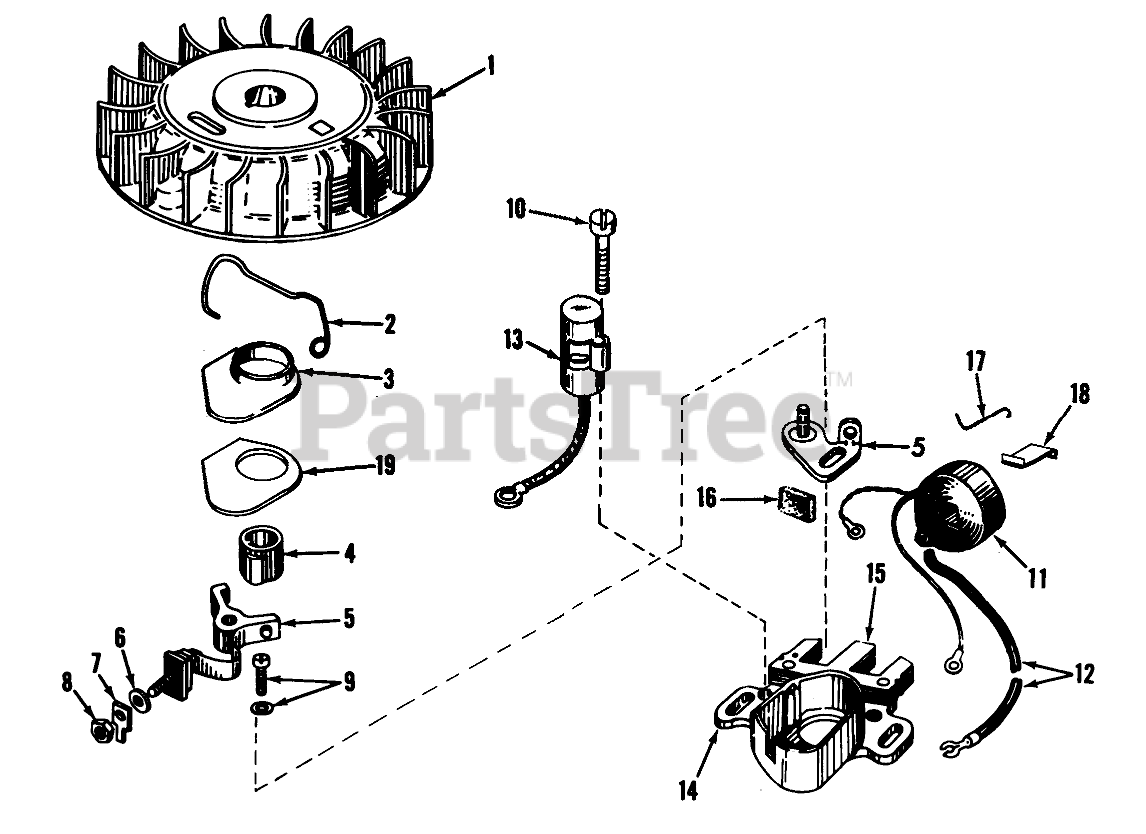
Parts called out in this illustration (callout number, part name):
1	Flywheel
2	Spring Breaker Box
3	Cover, Dust
4	Cam, Breaker
5	Breaker Assy.
7	Terminal
9	Breaker Screw
10	Condenser Screw
11	Coil Assy., (Incl. Ref. Nos. 12, 13 & 18)
12	Wire, Lead
13	Condenser
14	Core & Plate
15	Stator Assy., (Incl. Ref. Nos. 2, 3, 5 thru 14 & 16 thru 19)
16	Felt,Cam Wiper
17	Clip, Coil
18	Spring Coil Wedge
19	Gasket Dust Cover
